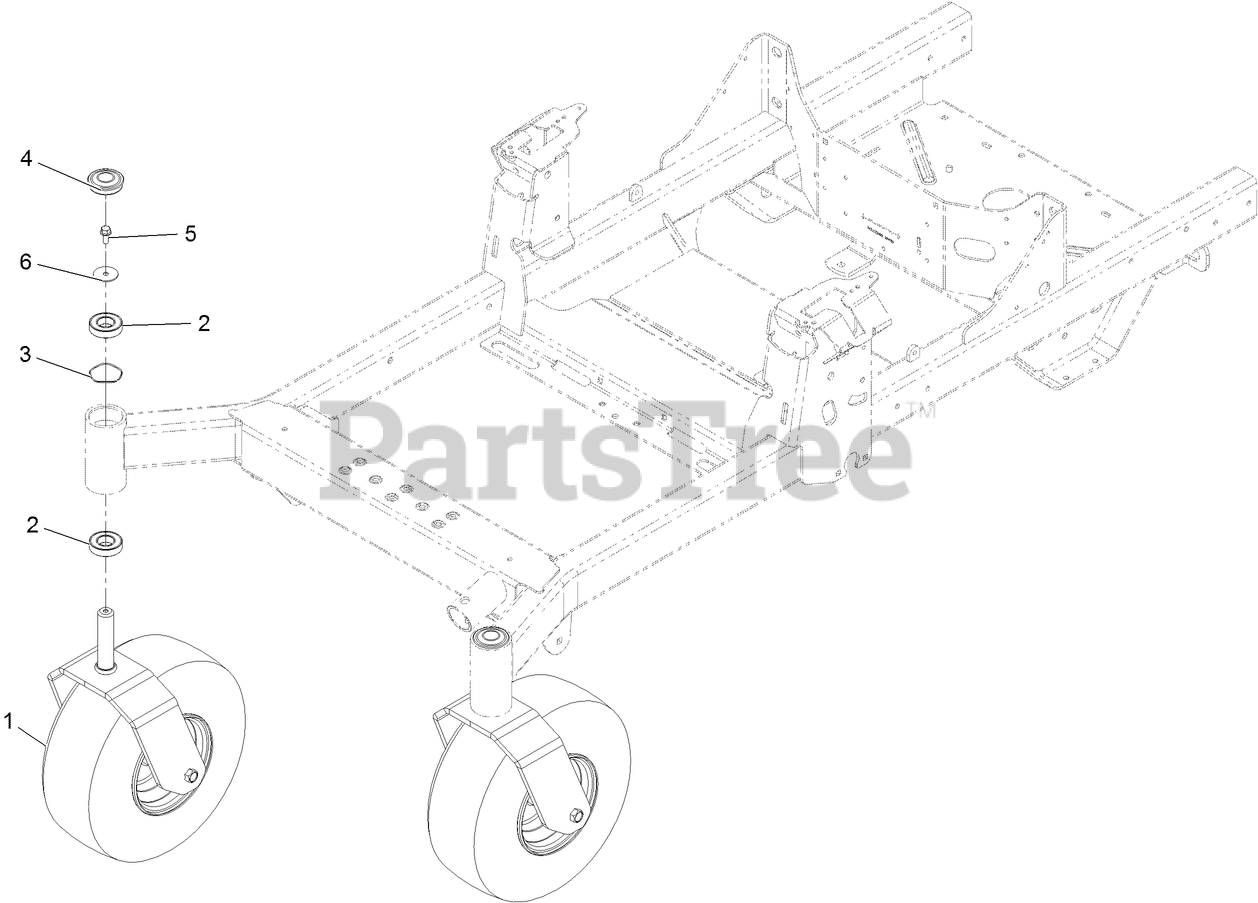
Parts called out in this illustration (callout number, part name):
1	ASM-Front Caster W/Fork
2	BEARING-BALL
4	CAP-GREASE
5	SCREW-HHF
6	WASHER-FLAT
